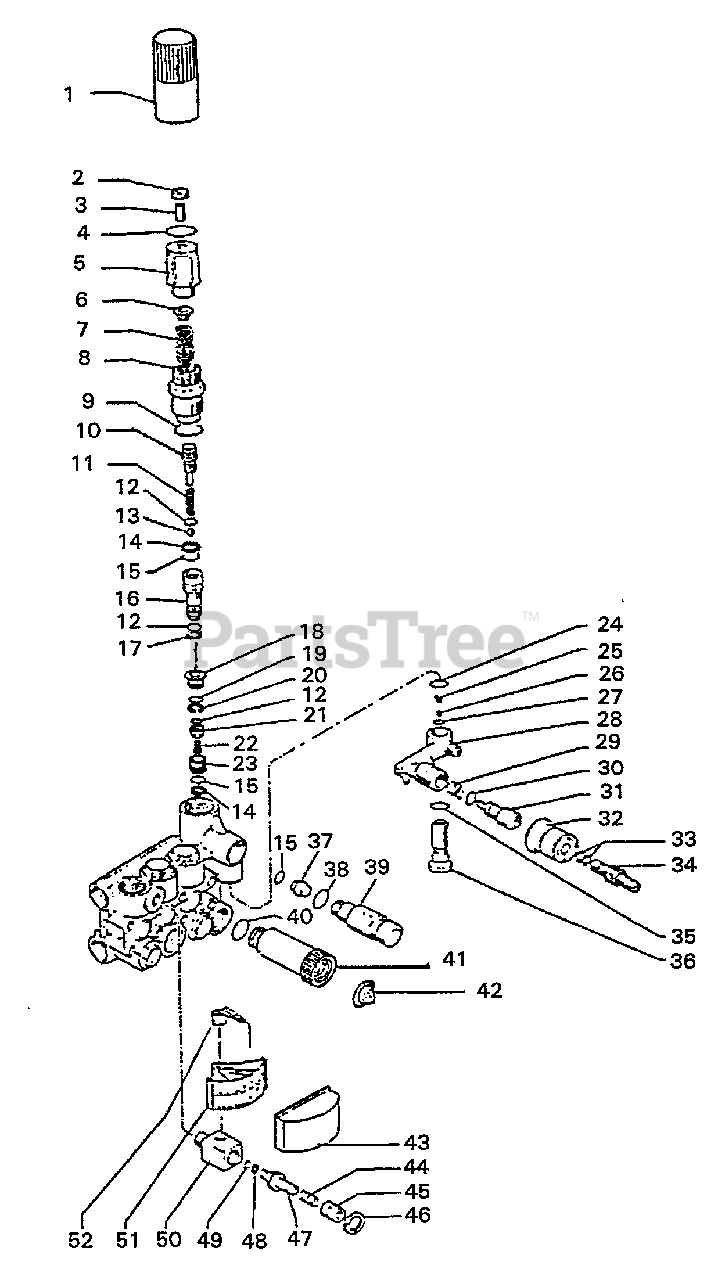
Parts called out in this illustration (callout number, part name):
1	KNOB, PRESSURE REGULATOR
2	NUT - 8
3	SCREW - 8X16
4	O-RING
5	SCREW, PRESSURE SET
6	PLATE, SPRING
7	SPRING
8	BUSHING, GUIDE
9	O-RING - .797 X.103
10	STOPPER, STROKE
11	SPRING
12	O-RING
13	BALL - 9/32"
14	RING, ANTI-EXTRUSION
15	O-RING
16	PISTON, CONTROL
17	RING, ANTI-EXTRUSION
18	GUIDE, VALVE
19	O-RING, .489 X.070
20	RING, ANTI-EXTRUSION
21	VALVE, BALL
22	SCREW - 5
23	SEAT, VALVE
24	O-RING
25	SPRING, TAPER
26	BALL
27	O-RING
28	BODY, INJECTOR
29	SPRING
30	O-RING
31	SHUTTER, INJECTOR
32	KNOB, CHEMICAL REGULATOR
33	O-RING
34	FITTING, HOSE BARB
35	O-RING
36	SEAT, CHEMICAL VALVE
37	NOZZLE, INJECTOR
38	O-RING
39	NIPPLE
41	NIPPLE
42	WASHER, STRAINER
43	COVER
44	SPRING
45	SCREW - 14X1
46	NUT - 14
47	PISTON
48	RING, BACK-UP
49	O-RING
50	BODY
51	DIAL
52	INDICATOR
